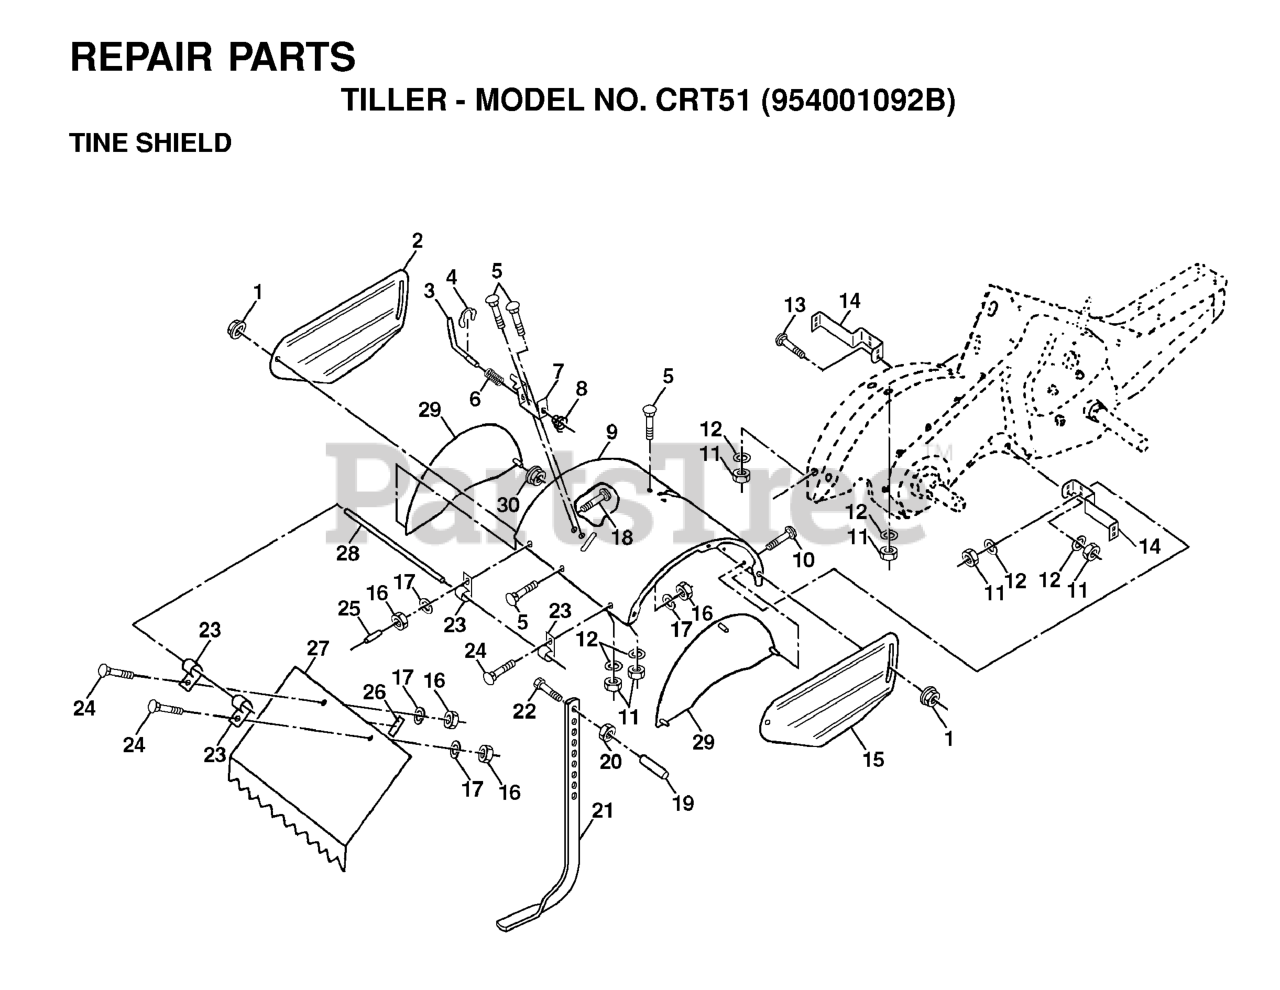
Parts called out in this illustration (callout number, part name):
1	HOUSING.AUGER.24.LS.ORANGE
2	PLATE.SHAVE.24.LS.SNOW.BLACK
3	BOLT
4	NUT.FLANGE.5/16
